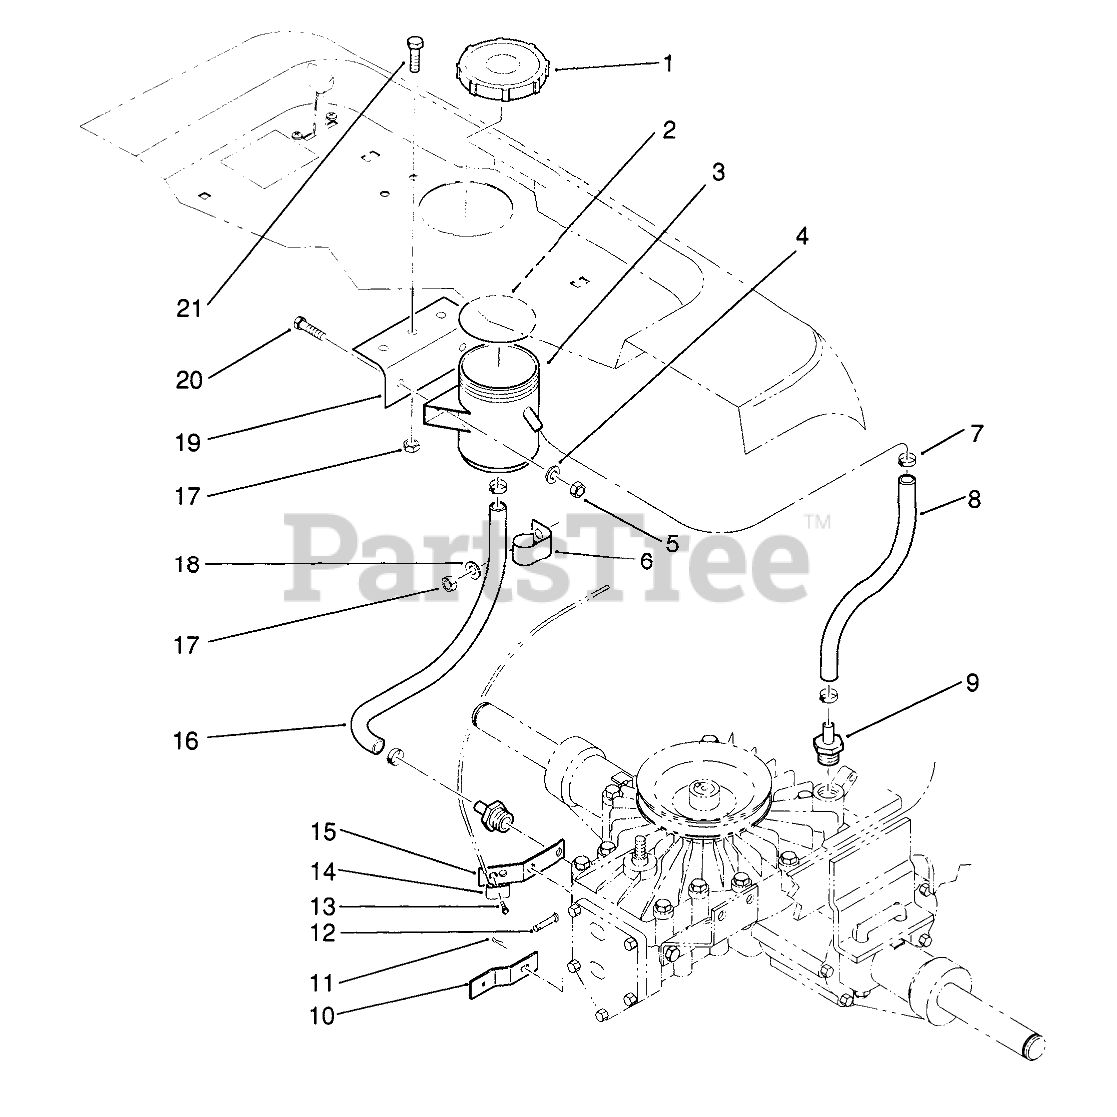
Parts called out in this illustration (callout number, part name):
1	COVER
2	COVER GASKET
3	RESERVOIR
5	Nut
6	CLIP
7	CLAMP
8	HOSE-RESERVOIR
9	Barb-Hose
10	Plate
11	Cotter Pin
13	Screw
14	CLAMP THROTTLE
15	PLATE-MTG
16	S/A 9" OF 114702
17	Nut
18	WASHER 5/16 SAE
19	BRACKET R
20	Bolt
21	Bolt
23	Cotter Pin
